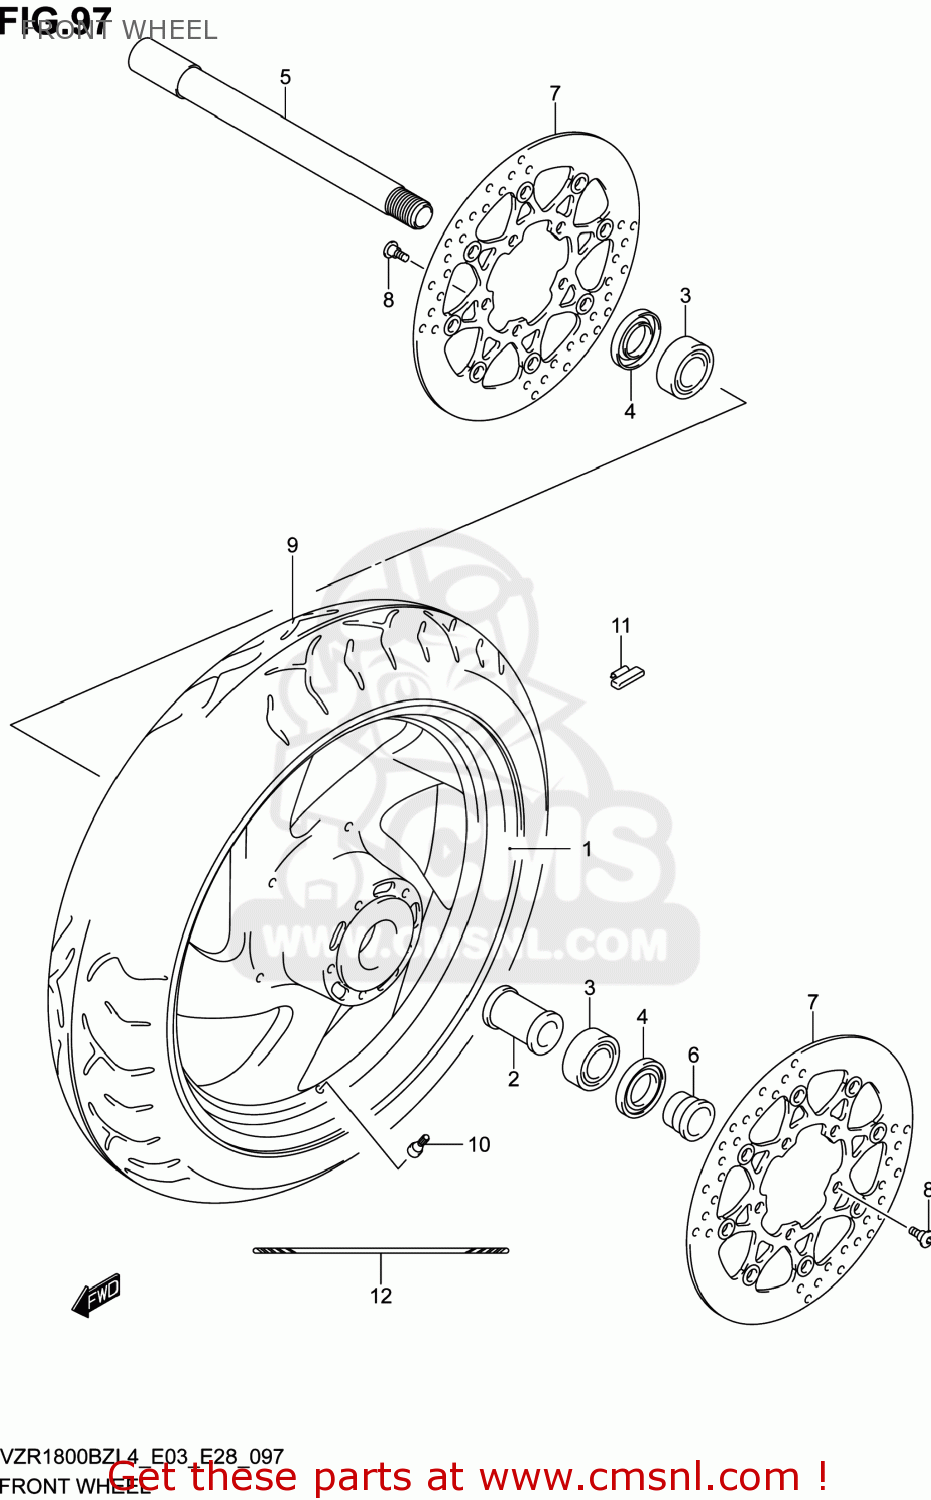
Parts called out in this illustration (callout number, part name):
1	WHEEL,FR(18M/CXMT3.50)
2	SPACER,FR WHEEL BEARING
3	BEARING(25X52X15)
4	SEAL,OIL(32X52X7)
5	AXLE,FR
6	SPACER,FR AXLE,L
7	DISC,FRONT BRAKE
8	BOLT(8X21)
9	TIRE,FR
10	VALVE ASSY,WHEEL RIM(TR412)
11	BALANCER,WHEEL(10G)
12	TAPE,WHEEL
